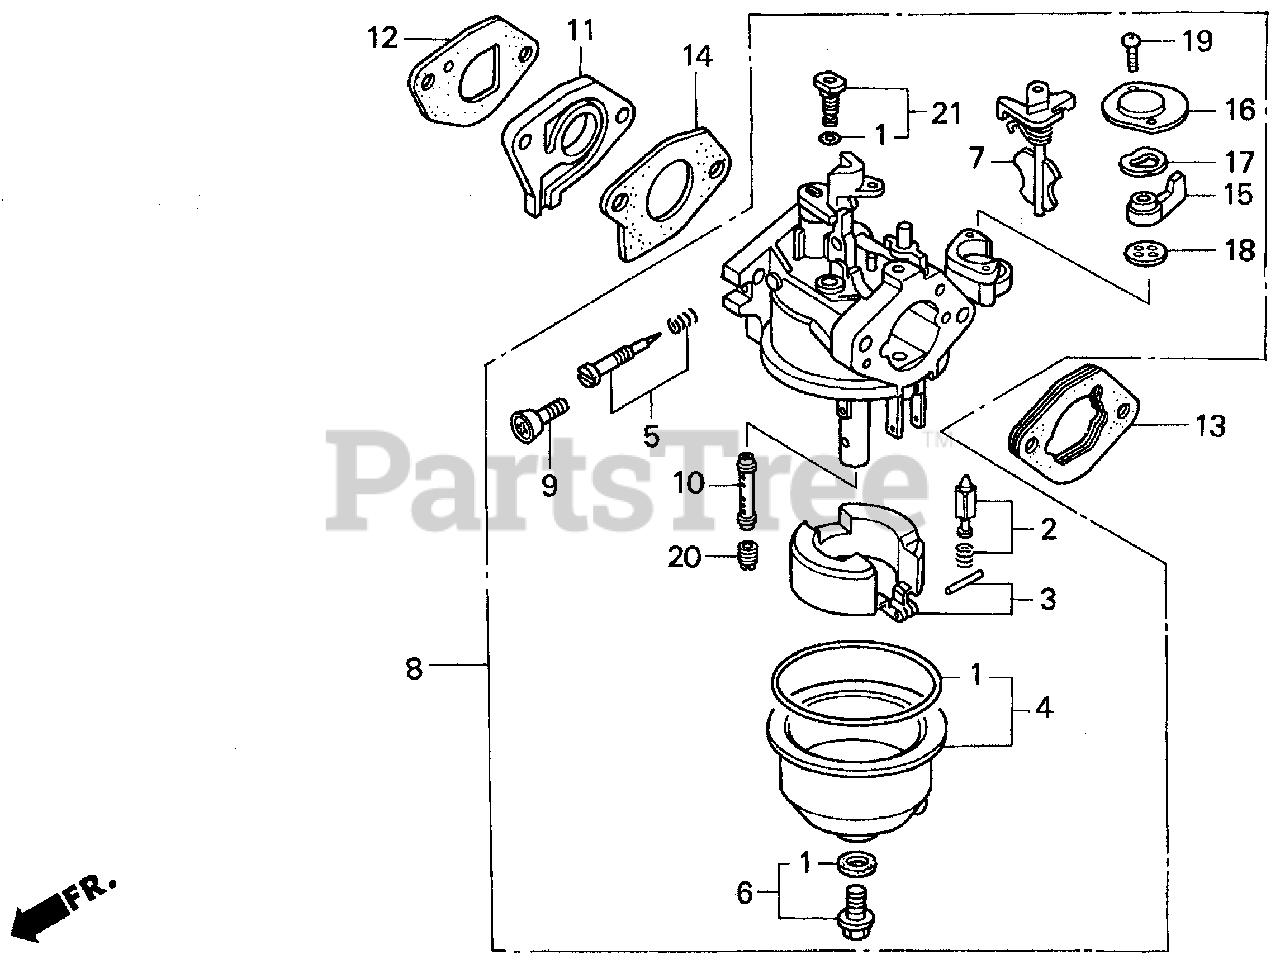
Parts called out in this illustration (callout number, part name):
1	GASKET SET
2	VALVE SET, FLOAT
3	FLOAT SET
4	CHAMBER SET, FLOAT
5	SCREW SET
6	SCREW SET B
7	CHOKE SET
8	CARBURETOR ASSY. (BE53A C)
9	SCREW, THROTTLE STOP
10	NOZZLE, MAIN
11	INSULATOR, CARBURETOR
12	GASKET, CARBURETOR (HPE)
13	SPACER, CARBURETOR
14	GASKET, CARBURETOR
15	LEVER, VALVE
16	PLATE, LEVER SETTING
17	SPRING, VALVE LEVER
18	GASKET, VALVE
19	SCREW, PAN (3X6)
19	SCREW, PAN (3X8)
20	JET, MAIN (#55)
20	JET, MAIN (#52)
20	JET, MAIN (#58)
21	JET SET, PILOT (#38)
